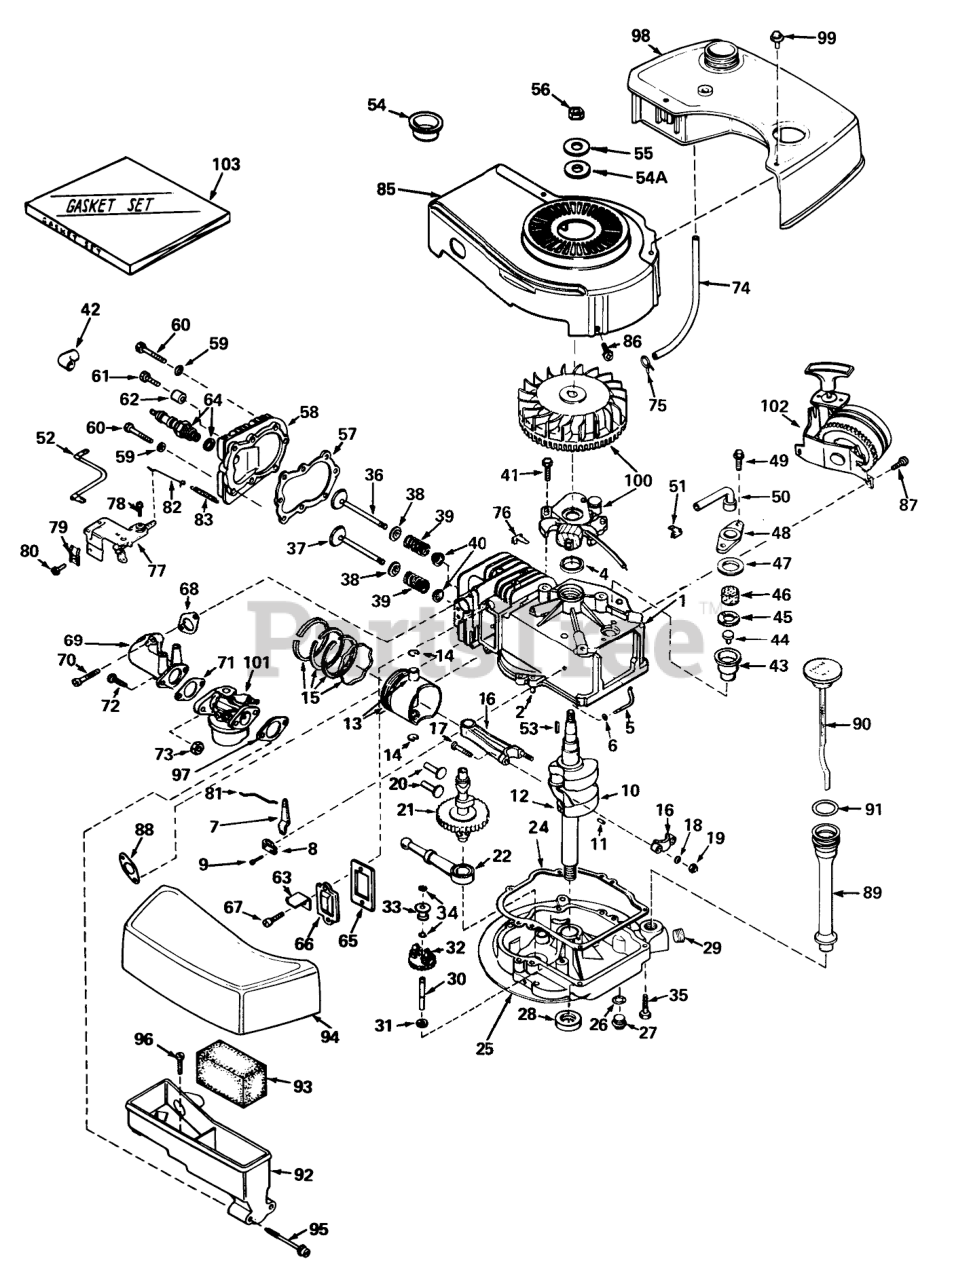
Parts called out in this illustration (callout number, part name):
1	Cylinder Assembly (Incl. Nos. 2, 4 & 87)
2	Pin-Dowel
4	OIL SEAL
5	Rod, Governor (Incl. No. 6)
6	Washer-Flat
7	Governor Lever
8	Clamp-Lever, Governor
9	Screw
10	Crankshaft (Incl. Nos. 11 & 12)
11	Pin, Groove
12	Gear, Crankshaft
13	Piston & Pin Assy., (Incl. 2 of No. 14) (Standard)
13	Piston & Pin Assy., (Incl. 2 of No. 14) (.010 Oversize)
13	Piston & Pin Assy., (Incl. 2 of No. 14) (.020 Oversize)
14	Ring-Retaining, Piston Pin
15	Ring Set Piston (Std.)
15	Ring Set Piston (.010 Oversize)
15	Ring Set Piston (.020 Oversize)
16	Rod Assembly, Connecting (Incl. Nos. 17, 18 & 19)
17	Bolt, Connecting
19	LOCKNUT
20	Lifter-Valve
21	Camshaft (Mech. Compression Release)
22	Oil Pump ASM
24	Gasket, Mounting
25	Flange Assembly, Mounting (Incl. Nos. 27, 28, 29 & 30)
26	Gasket-Oil Drain
27	Plug Oil Drain
28	Seal Oil
29	Plug Oil Drain
30	Shaft-Governor
31	Washer-Flat
32	Governor Gear ASM
33	Spool-Governor
34	Ring-Retaining
35	Screw (1/4-20 x 1-1/4)
36	Valve, Intake (Standard) (Incl. Nos. 38, 39 & 40)
36	Valve, Intake (1/32" Oversize) (Incl. Nos. 38, 39 & 40)
37	Valve, Exhaust (Standard) (Incl. Nos. 38, 39 & 40)
37	Valve, Exhaust (1/32" Oversize) (Incl. Nos. 38, 39 & 40)
38	Cap-Upper Valve Spring
39	Spring-Valve
40	Cap-Valve, Spring
42	Cover-Spark Plug
43	Body Breather Tube
44	Valve Check
45	2000A37 WIZARD ROTA
46	Element-Breather
47	Gasket-Breather
48	Cover Breather
49	Screw, Hex Hd. w/Conical
50	Tube, Breaker
51	Clip, Breather
52	Wire, Ground
53	Key Flywheel
54A	Washer Flat
55	Washer
56	Hex Nut
57	Oil Fill Tube
58	Head Cylinder
60	Screw
61	Screw Hex Hd. Cap
63	Retainer Clip
64	Plug, Spark (J17LM or equiv.)
65	Gasket-Breather
66	Cover-Valve
67A	Terminal
68	Gasket, Intake
69	Pipe, Intake
70	Screw (1/4-20 x 1)
71	Gasket-Carburetor
72	Screw
73	Nut and Lock Washer (1/4-28)
74	Line, Fuel
75	Clamp-Line, Fuel
78	Screw (10-24 x 3/4)
79	Conduit
80	Screw (10-32 x 3/8)
81	Link Governor
82	Link Governor Spring
83	Spring Governor
85	Housing, Blower
86	Screw
87	Screw (1/4-20 x 1/2)
88	Gasket Exhaust
89	Tube, Oil Filler
90	Dipstick, Oil (Incl. No. 91)
92	Body Air Cleaner
93	Filer, Air
94	Cove, Air Cleaner
95	Screw Fil Hd.
96	Screw, Hex Hd.
97	Gasket-Air Cleaner
98	Tank Fuel
99	Screw (10-32 x 35/64)
100	Magneto
101	Carburetor
102	Starter, Side Mount
103	53024/VAR.16HP O/P
